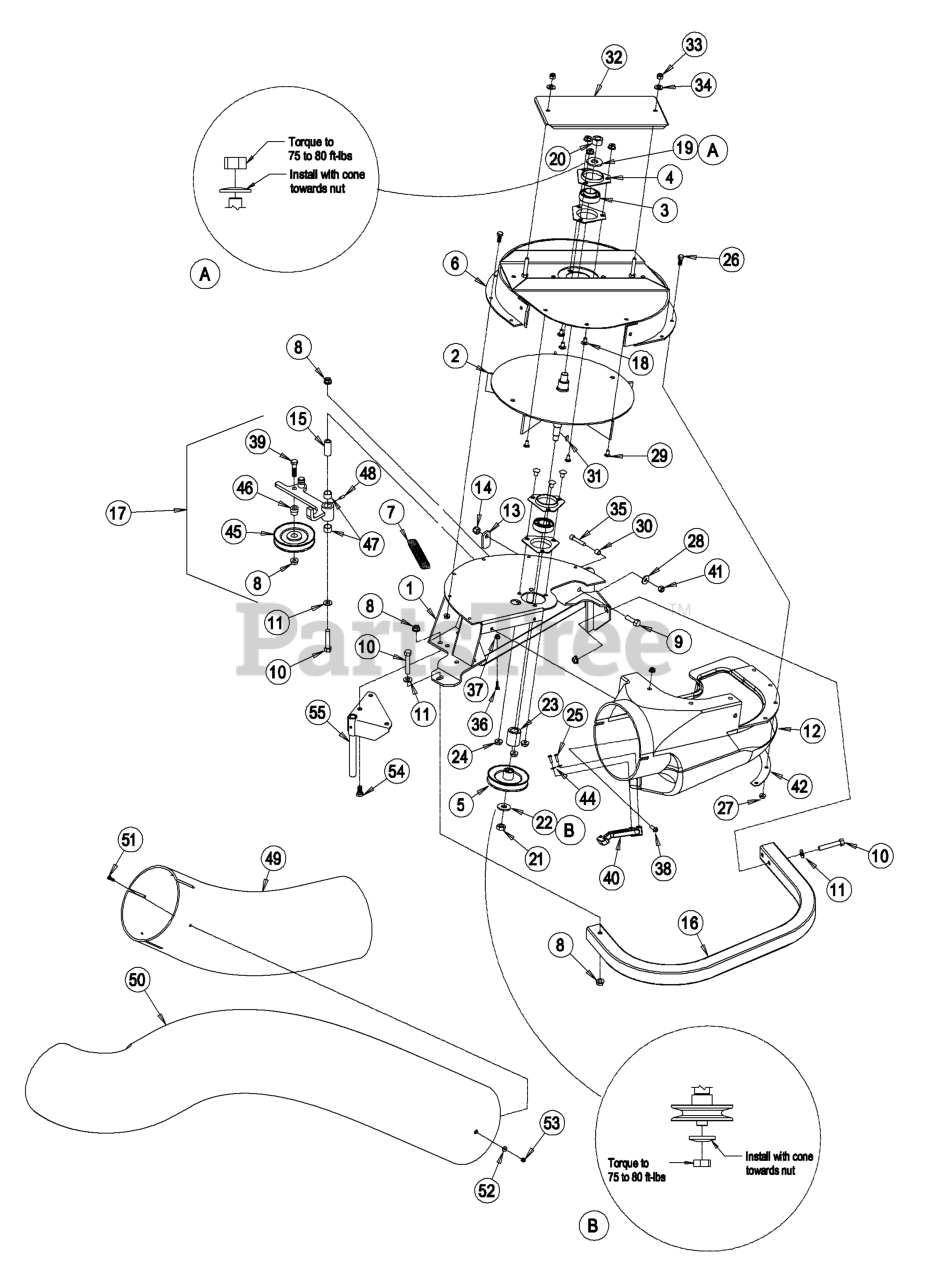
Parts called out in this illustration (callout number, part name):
3	BEARING
4	HOUSING-FLANGE
5	SHEAVE
7	SPRING-IDLER
8	NUT-HHF, WHIZ
9	SCREW-HH
10	SCREW-HH
11	WASHER-FLAT
12	CHUTE, BLOWER
13	LATCH-CATCHER, GRASS
14	NUT-LOCK, NI
15	BUSHING
17	ASM, IDLER ARM - SERVICE
18	SCREW-CARR
19	WASHER-SPRING
20	NUT-HEX
21	NUT-JAM
22	WASHER-SPRING
25	SCREW-PPH
26	SCREW-HH
28	WASHER-SPRING
29	SCREW-CARR
30	BUSHING, LOCATOR
31	KEY-WOODRUFF
33	NUT-LOCK, NI
34	WASHER-FLAT
35	SCREW-HSH
36	SCREW-HEAD, TRUSS
39	SCREW-HH
40	LATCH DRAW
41	NUT-HEX
42	PLATE-BACKING, BLOWER
44	WASHER-FLAT
46	HUB,SPACER
47	BUSHING
48	FITTING-GREASE
51	SCREW-HEAD, TRUSS
52	WASHER-FLAT
53	NUT-LOCK, NI
54	SCREW-HH
55	PIN-MOUNT
